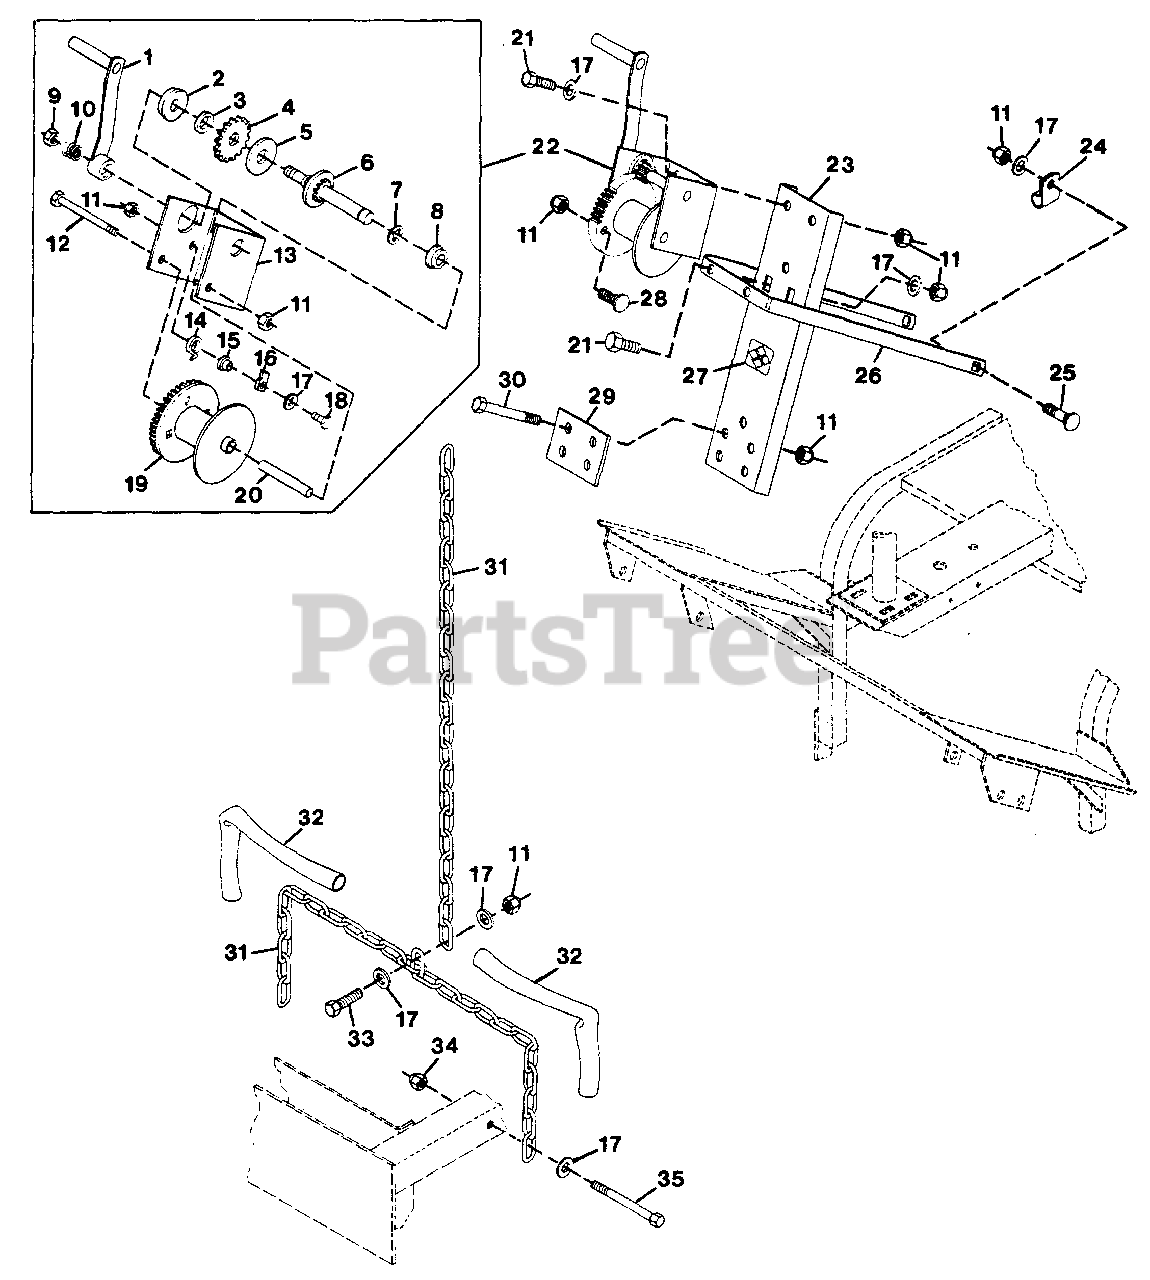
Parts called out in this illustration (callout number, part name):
1	Handle, Winch
2	Bushing, Shaft
3	Washer, Pressure
4	Wheel, Ratchet
5	Plate, Pressure
6	Shaft, Drive
7	E-Ring, .625 Shaft
8	Bushing, Shaft
9	Nut, Handle
10	Spring, Handle
11	Nut, Lock 3/8-16
12	Bolt, Hex 3/8-16x4.50
13	Base, Winch
14	Spring, Ratchet
15	Spacer, Ratchet
16	Pawl, Ratchet
17	Washer, Flat .406x.812x.065
18	Bolt, Ratchet
19	Reel, Winch
20	Spacer, Tubing
21	Bolt, Hex 3/8-16x1.00
22	Winch
23	Channel, Winch Lift
24	Clamp, Nylon
25	Bolt, 3/8-16x1.25 Rd Hd Sq Nk
26	Brace
27	Decal, Commercial Front
28	Bolt, 3/8-16x.875 Rd Hd Sq Nk
29	Plate, Channel Clamp
30	Bolt, Hex 3/8-16x2.5
31	Chain, Mower Lift
32	Tubing
33	Bolt, Hex 3/8-16x1.125
34	Nut, Lock 5/16-24
35	Bolt, Hex 5/16-24x2.75
